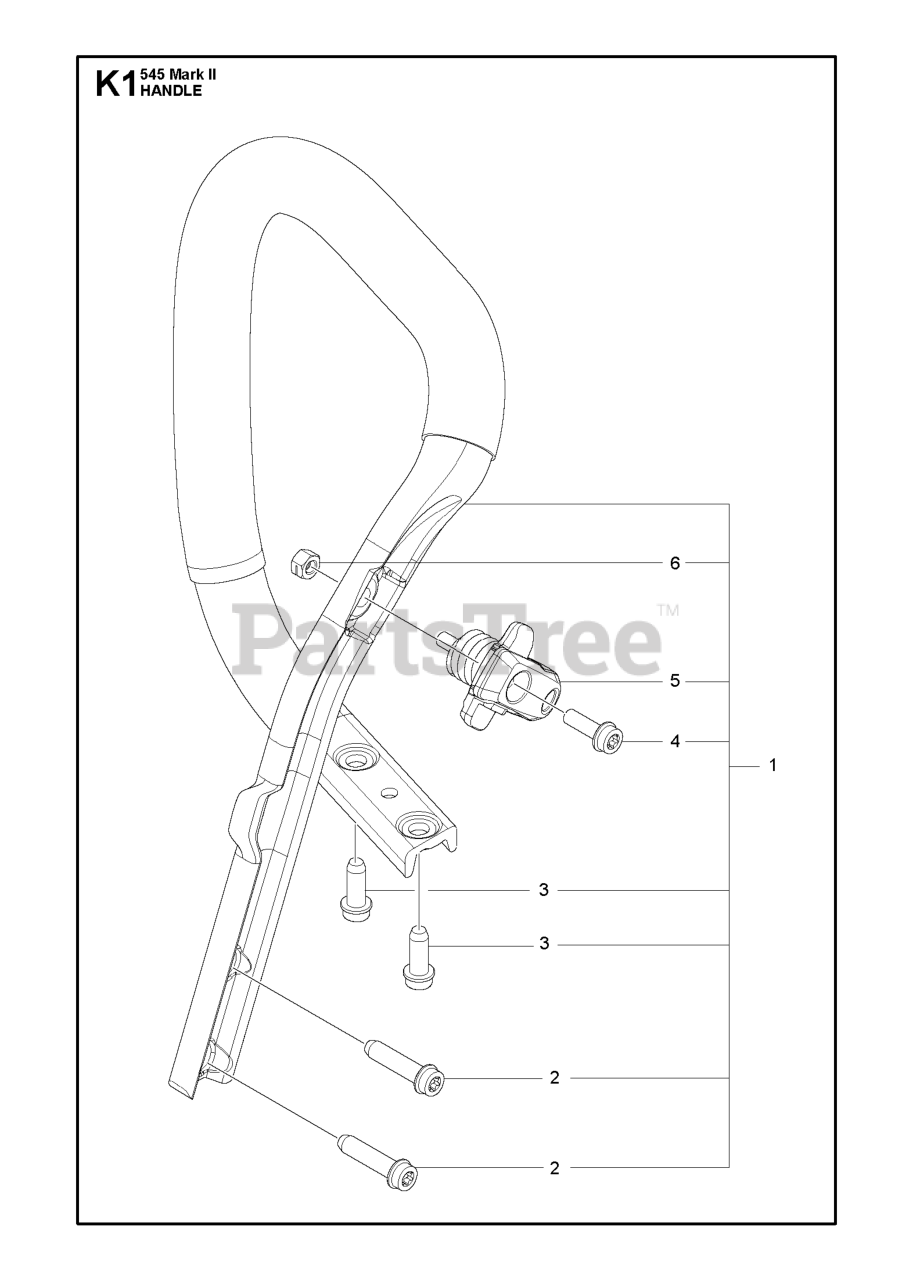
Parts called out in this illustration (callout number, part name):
1	HANDLE SYSTEM 50CC GEN 2
3	SCREW ITXSCFT PL6X16 T27 10.9
5	ANTIVIBRATION ELEMENT ASSY ALU
